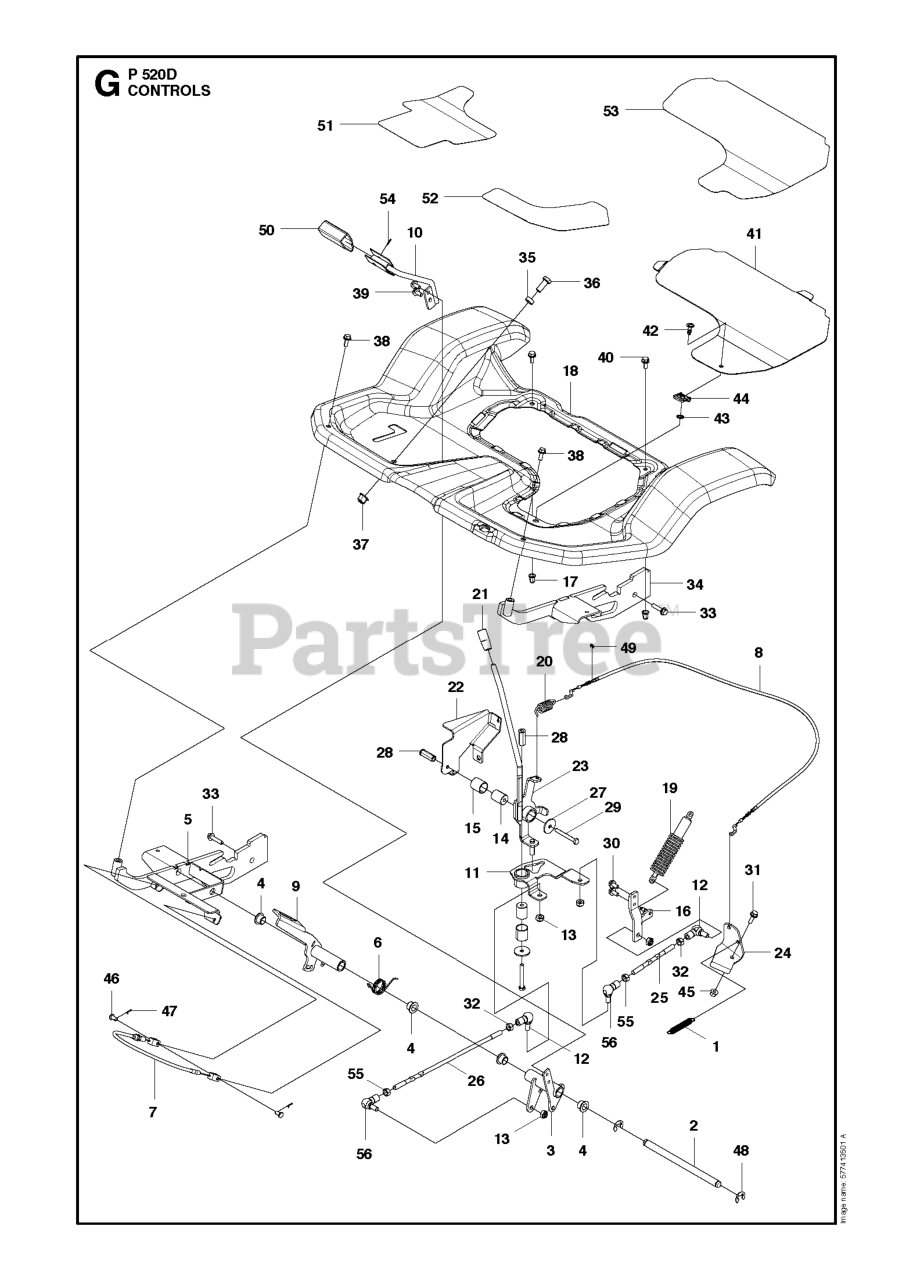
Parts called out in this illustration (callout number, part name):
4	BUSHING
12	LINK
15	BUSHING
19	SHOCK ABSORBER
31	BOLT
32	NUT
33	SCREW EHHFM
36	Hex Head Capscrew, M12 X 1.75 X 30 DIN933ZP
38	SCREW EHHFM
45	NUT FLANGE
46	Clevis Pin
47	Cotter Pin
50	PEDAL RUBBER
55	NUT
